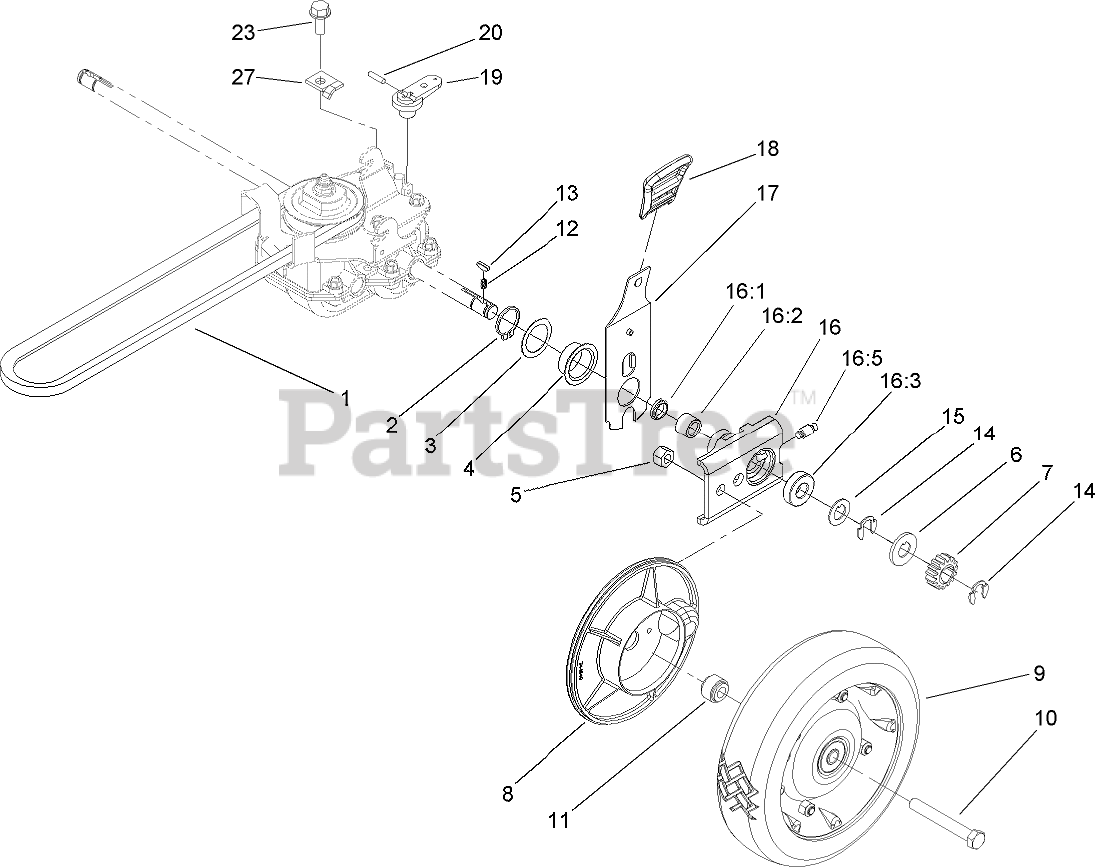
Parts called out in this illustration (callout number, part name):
1	V-BELT
2	RING-RETAINING
3	WASHER
4	CAP-END
5	NUT-LOCK, CONE
6	WASHER-THRUST, OUTER
7	GEAR-PINION
8	COVER-WHEEL
9	Wheel And Tire ASM
10	SCREW-HH
11	SPACER-COVER, WHEEL
12	SPRING-COMPRESSION
14	RING-RETAINING
15	WASHER-THRUST, OUTER
16	PIVOT ARM ASM
16:1	SEAL-OIL
16:2	BEARING-CAGED NEEDLE ROLLER
16:3	BEARING-WHEEL
17	REAR SPRING ARM ASM
18	KNOB-HOC
19	LEVER-SHIFT
20	PIN-COIL
23	SCREW-HWHTF
27	CLAMP-CABLE
